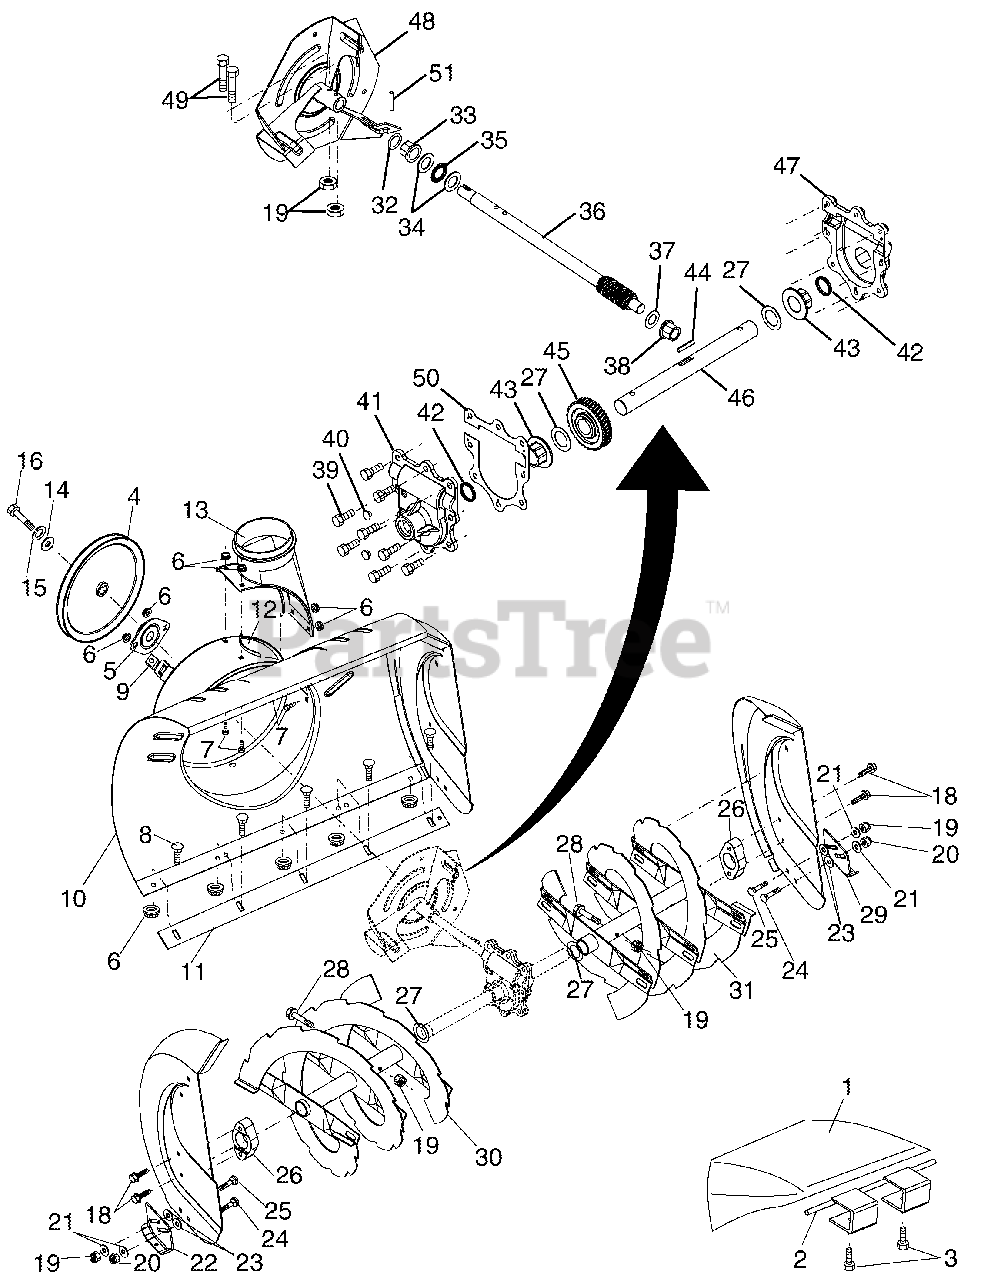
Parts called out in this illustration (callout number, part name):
1	Bag, Weight
2	Bracket, Weight Bag
3	Screw, Hex Head 5/16-18 x 1-1/2
4	Pulley, Impeller
5	Bearing Assembly, Flange
6	Nut, Hex Flange 5/16-18
7	Bolt, Flat Head, Carriage 5/16-18 x 5/8
8	Bolt, Carriage 5/16-1 8 x 5/8
9	Nut, Cage 3/8-16
10	Housing, Auger
11	Bar, Scraper
12	Bracket, Corner Discharge
13	Base, Discharge Chute
14	Washer, Flat
15	Washer, Lock 5/16
16	Screw, Hex Head 5/16-18 x 3/4
18	Screw, Hex Head 5/16 x 1
19	Nut, Hex Lock 1/4-20
20	Nut, Hex Lock 5/16-18
21	Washer, Flat
22	Skid Plate, RH
23	Washer, Nylon, Friction
24	Bolt, Carriage 5/16-18 x 3/4
25	Bolt, Shoulder
26	Bearing, Auger
27	Washer, Thrust, 1"
28	Bolt, Shoulder 1/4-20 x 2
29	Skid Plate, LH
30	Auger Assembly, RH
31	Auger Assembly, LH
32	O-Ring
33	Bushing, Flange 3/4
34	Washer, Thrust 3/4
35	Bearing, Thrust 3/4
36	Shaft, Impeller
37	Washer, Thrust 5/8
38	Bushing, Flange 5/8
39	Screw, Hex Head 5/16-18 x 3/4
40	Plug, Case
41	Housing, Gearbox, RH
43	Bushing, Flange, 1"
44	Key, Square 1/4 x 1/4 x 7/8
45	Gear, Worm
46	Shaft, Auger
47	Housing, Gearbox, LH
48	Impeller Assembly
49	Screw, Hex Head 1/4-20 x 1-5/8
50	Gasket, Gearbox
51	Pin, Roll 3/16 x 1-1/8
